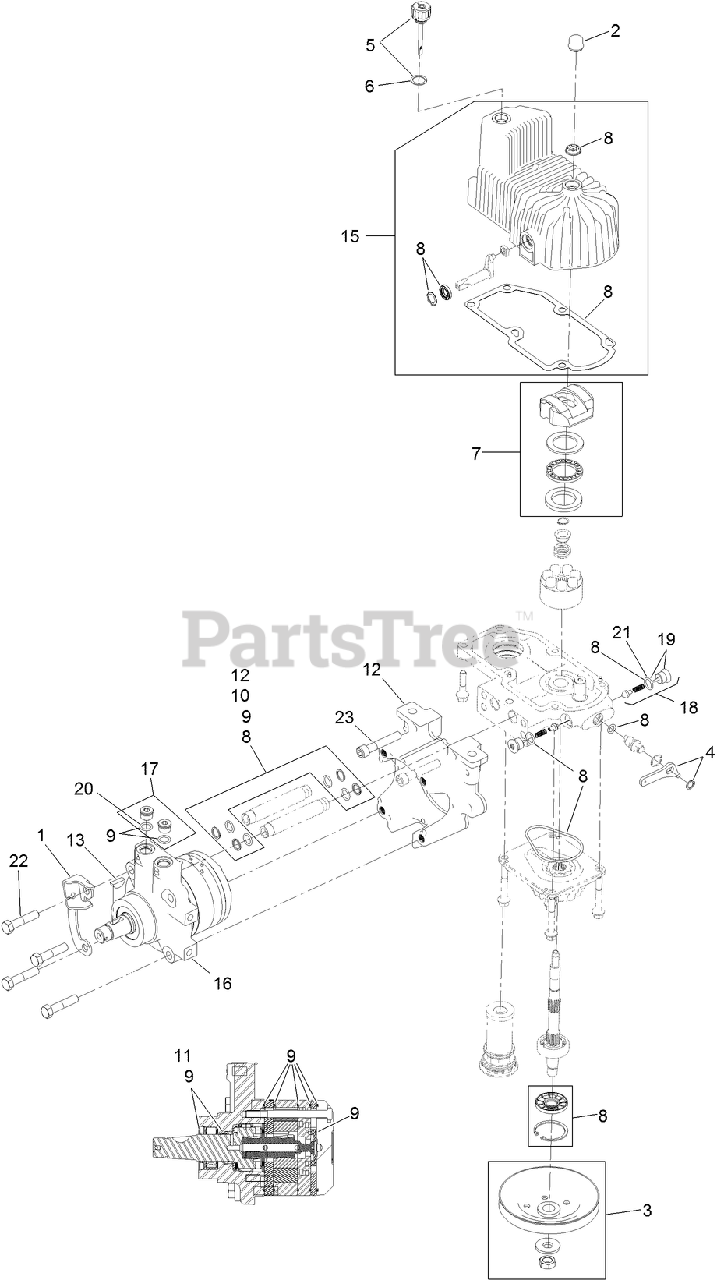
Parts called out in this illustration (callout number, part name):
1	BRACKET-ANCHOR, CABLE
2	COVER-SHAFT, HYDRO
3	PULLEY KIT
4	HANDLE-BYPASS VALVE, HYDRO
5	DIPSTICK-HYDRO W/GASKET
6	GASKET-DIPSTICK, HYDRO
7	SWASH BLOCK KIT
8	PUMP SEAL KIT
9	MOTOR SEAL KIT
10	TUBE SEAL KIT
11	OUTPUT SHAFT SEAL KIT
12	NOSE CUP-UHT
13	KEY-WOODRUFF
15	Housing-LH
16	MOTOR-HYDRAULIC LH 240CC
17	MAGNETIC PLUGS SERVICE KIT
18	CHECK VALVE ASM
19	PLUG-CHECK (W/O-RING)
20	O-RING
21	O-RING-CHECK VALVE
22	SCREW HH
23	SCREW-HSH
